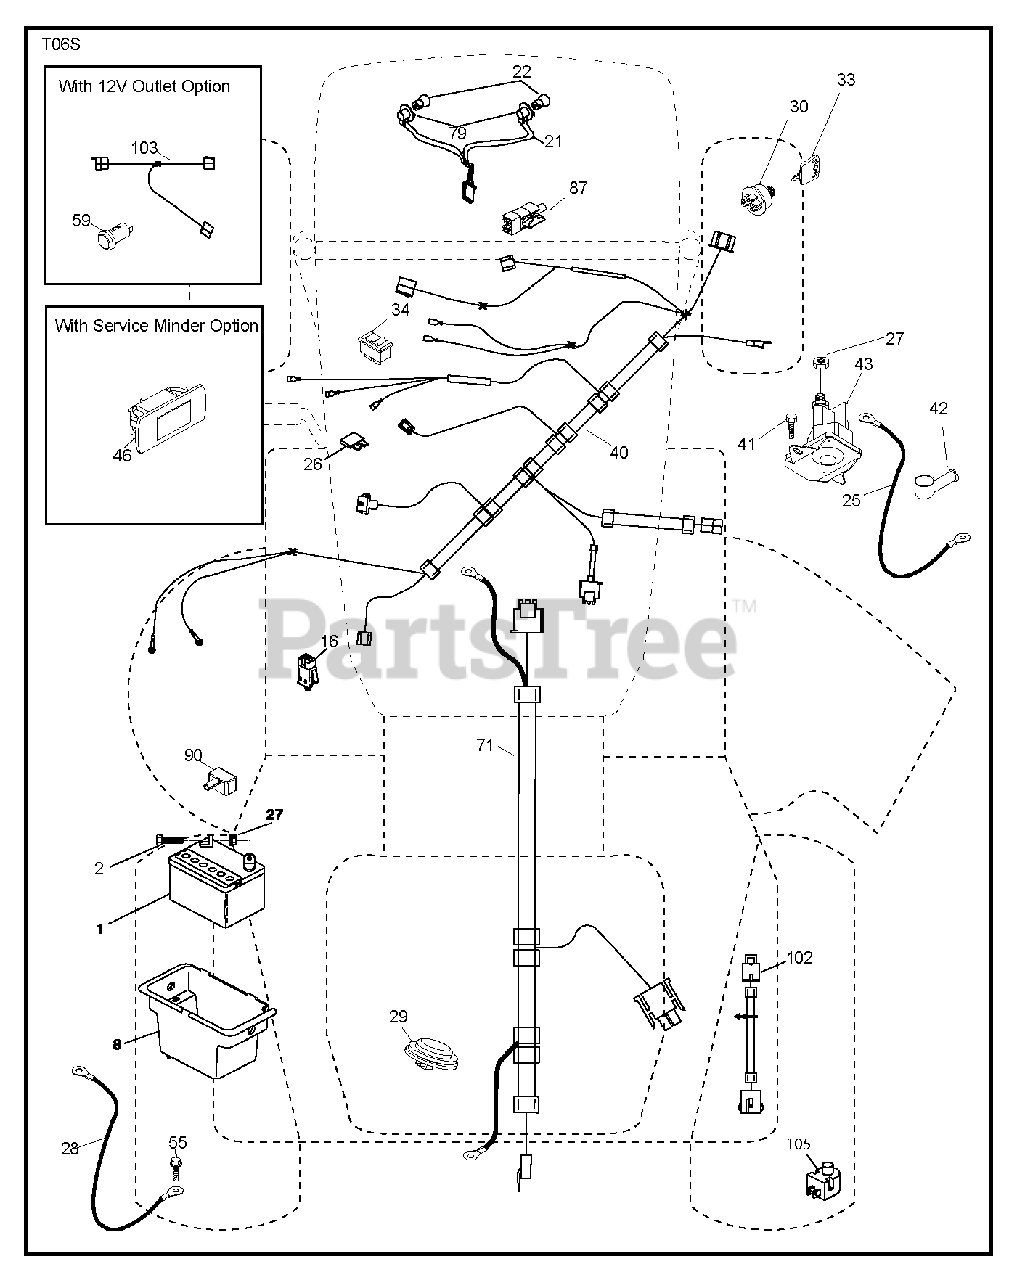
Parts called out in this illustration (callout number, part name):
1	REPL BY 532 12 38-99
2	BOLT.HEX.1/4.X.3/4.DICHROMATE
8	BOX.BATTERY.MNT.REAR.L
16	SWITCH INTERLOOK PUSH-IN
21	HARNESS ASSY LIGHT
22	LIGHTBULB
25	CABLE.STARTER.6G.BL/RED.17.5
26	FUSE 20AMP
27	NUT
28	CABLE.BLACK.18"REAR.BA
29	SWITCH.SEAT.DELTA.OPC.
30	SWITCH.IGN.DELTA.W.LGH.ROS
33	KEY.CHAIN.BLISTER.PACK.GEN.USA
34	SWITCH LT
40	HARNESS IGN. DASH
41	SCREW
42	TERMINAL COVER
43	SOLENOID.W/BRASS.PLUNGER
46	GUAGE.SRVCMNDR.HRMTR.
55	SCREW 5/16"
71	HARNESS.IGN.CHASS.TEX.REAR.BAT
79	BULB HOLDER ASM.
87	SWITCH.INTRLCK.CLUTCH.
90	COVER.TERMINAL.BATTERY
102	HARNESS PIGTAIL PCH TEX ROS
105	REVERSE SWITCH
